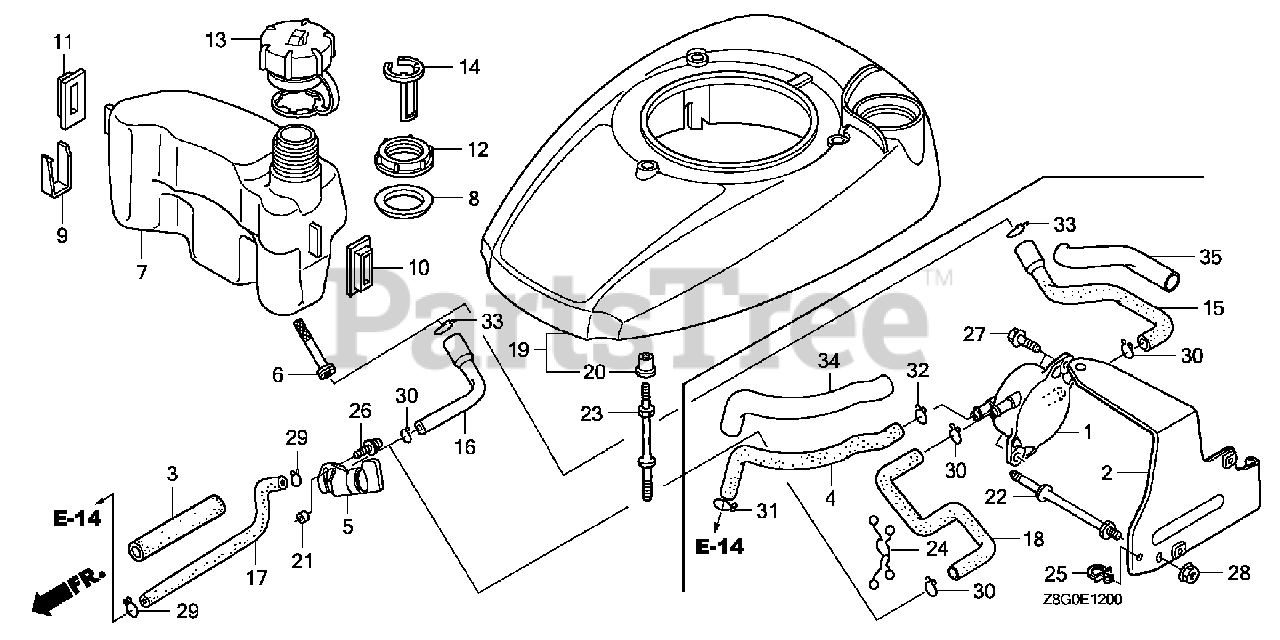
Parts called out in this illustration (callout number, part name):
1	PUMP ASSY., FUEL
2	STAY, FUEL PUMP
3	RUBBER, SUPPORTER (107MM)
4	TUBE, DIAPHRAGM
5	PETCOCK ASSY.
6	FILTER, FUEL
7	TANK, FUEL
8	SEAL, FUEL FILLER NECK
9	CLIP, TANK MOUNTING
10	RUBBER A, TANK MOUNTING
11	RUBBER B, TANK MOUNTING
12	NUT, TANK MOUNTING
13	CAP ASSY., FUEL TANK
14	GAUGE, FUEL LEVEL
15	TUBE, FUEL TANK
17	TUBE, FUEL
18	TUBE B, FUEL
19	COVER, FAN *NH1* (BLACK)
20	COLLAR, FAN COVER
21	COLLAR, FR. TURN SIGNAL
22	BOLT, STUD
23	BOLT, STUD (H=42.5MM)
24	CLIP, PURSE LOCK
25	CLIP, WIRE HARNESS
26	SCREW-WASHER (5X10)
27	SCREW-WASHER (5X14)
28	NUT, FLANGE (6MM)
29	CLIP, TUBE (B8)
30	CLIP, TUBE (B10)
31	CLIP, TUBE (C8)
32	CLIP, TUBE (C9)
33	CLIP, TUBE (C11)
34	BULK HOSE, VINYL (9X11X3000) (9X11X210)
35	BULK HOSE, VINYL (13X15X8000) (13X15X90)
